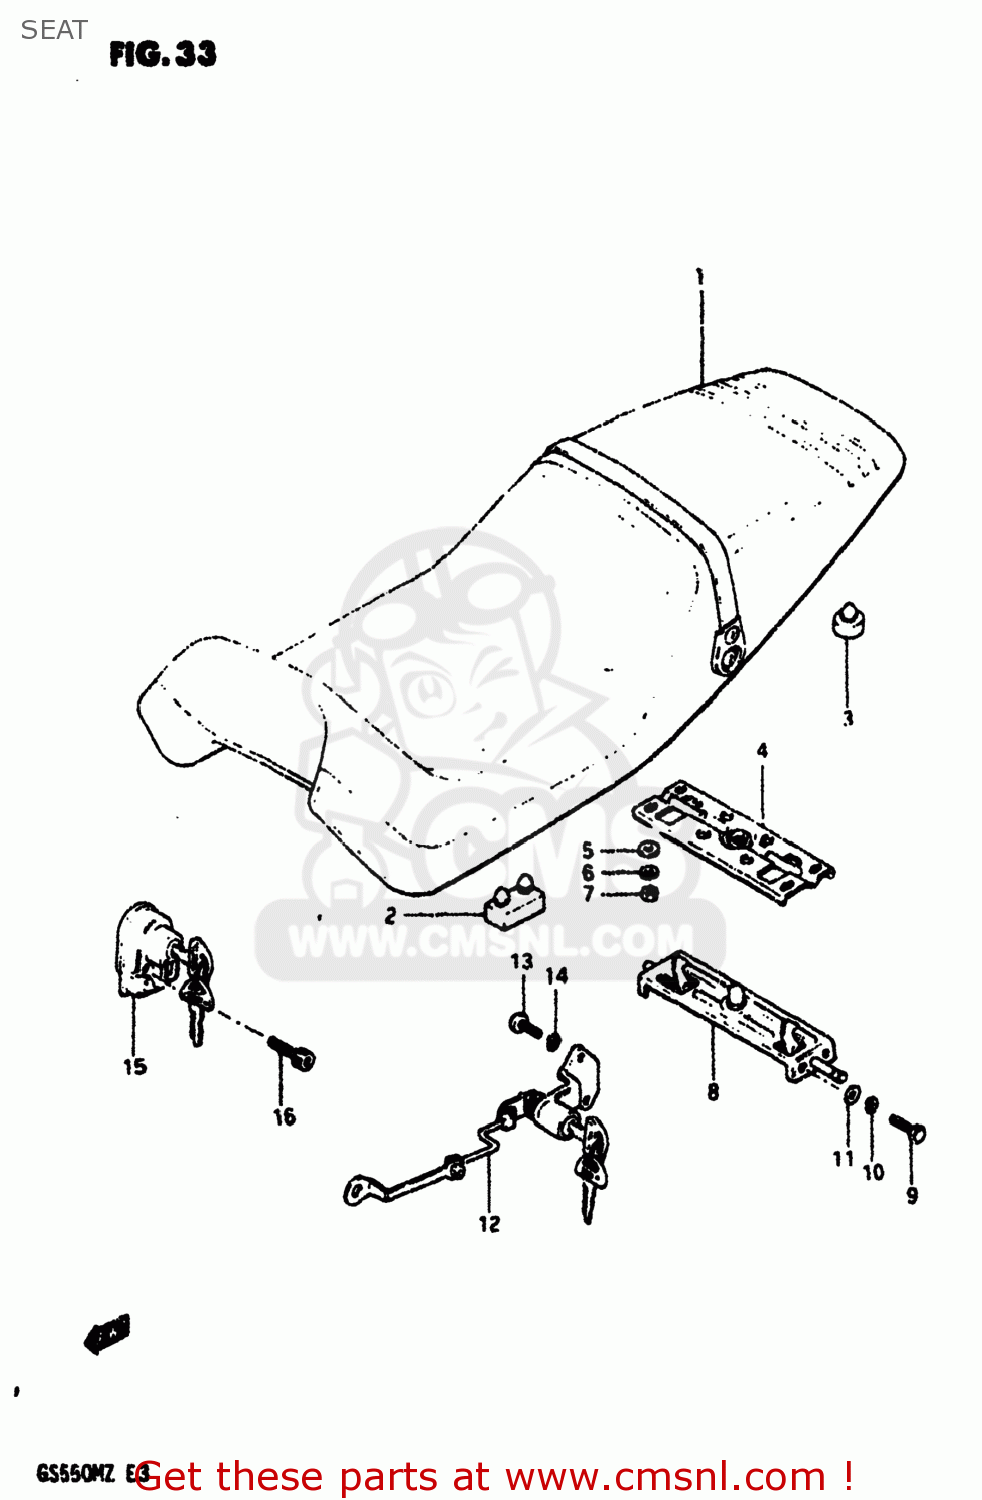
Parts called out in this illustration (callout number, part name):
1	SEAT ASSEMBLY
2	CUSHION
3	CUSHION
4	PLATE,SEAT LOCK GUIDE
5	WASHER
6	LOCK WASHER
7	NUT 6MM
8	PLATE,CLAMP GUIDE
9	BOLT
10	LOCK WASHER
11	WASHER
12	LOCK ASSEMBLY,SEAT
13	BOLT
14	LOCK WASHER
15	LOCK ASSY,HELMET
16	BOLT 5X25
